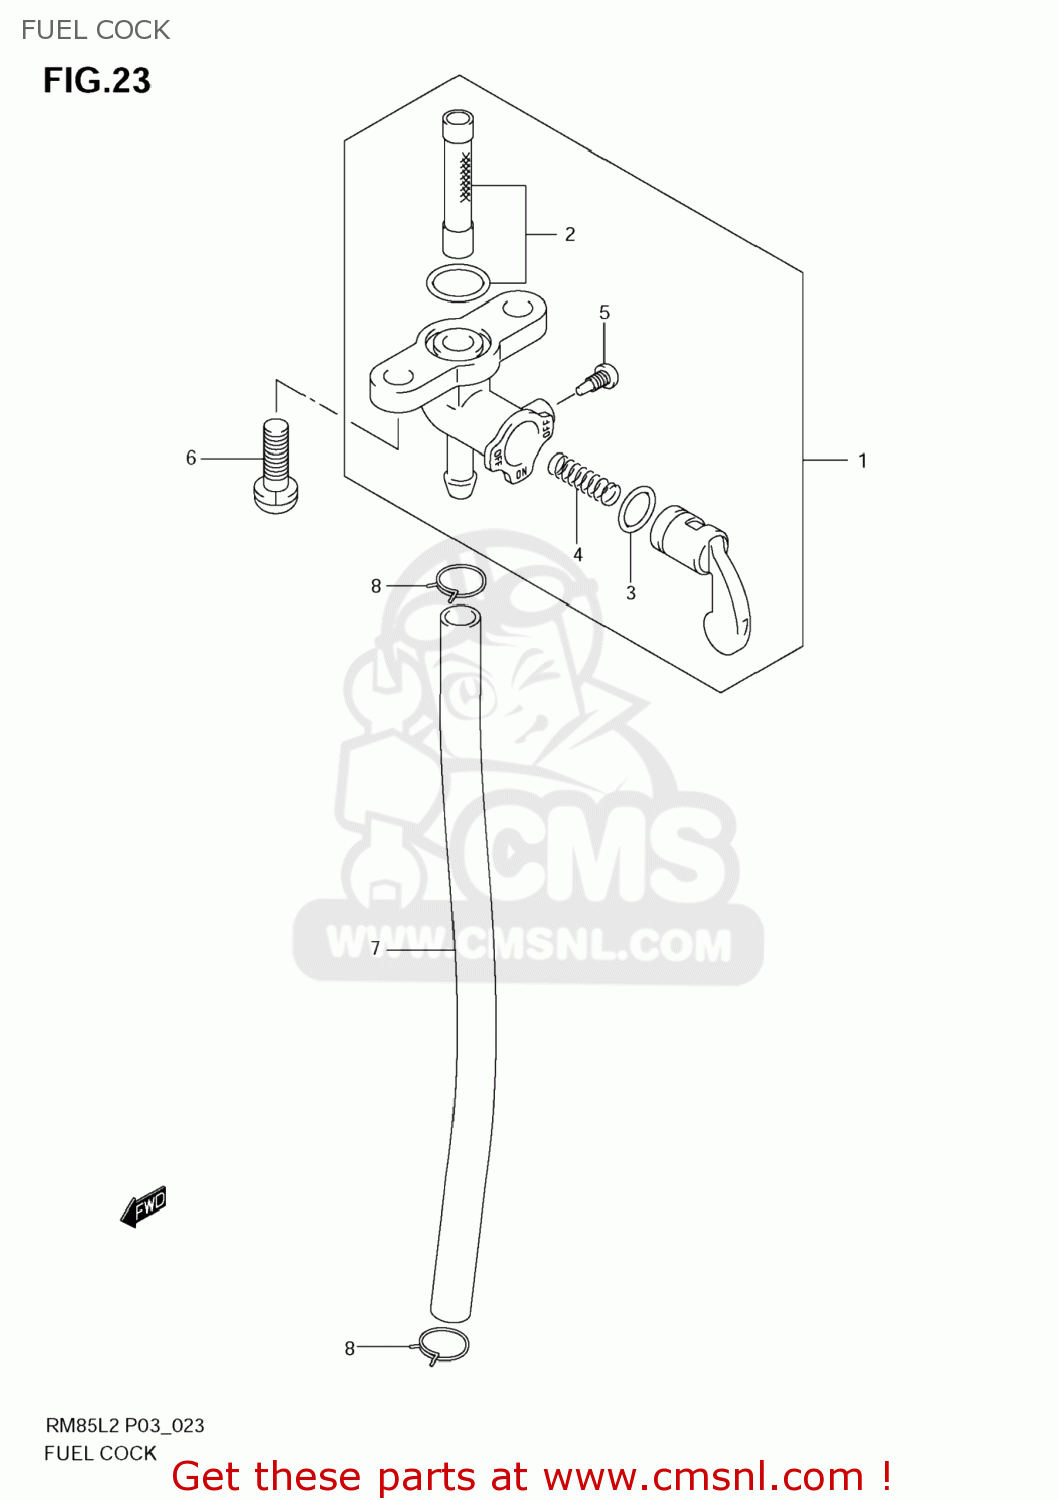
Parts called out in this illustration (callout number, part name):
1	COCK ASSY,FUEL
2	FILTER SET FUEL
3	O RING,LEVER
4	SPRING
5	SCREW
6	SCREW
7	HOSE(5X8.2X600)
8	CLIP
